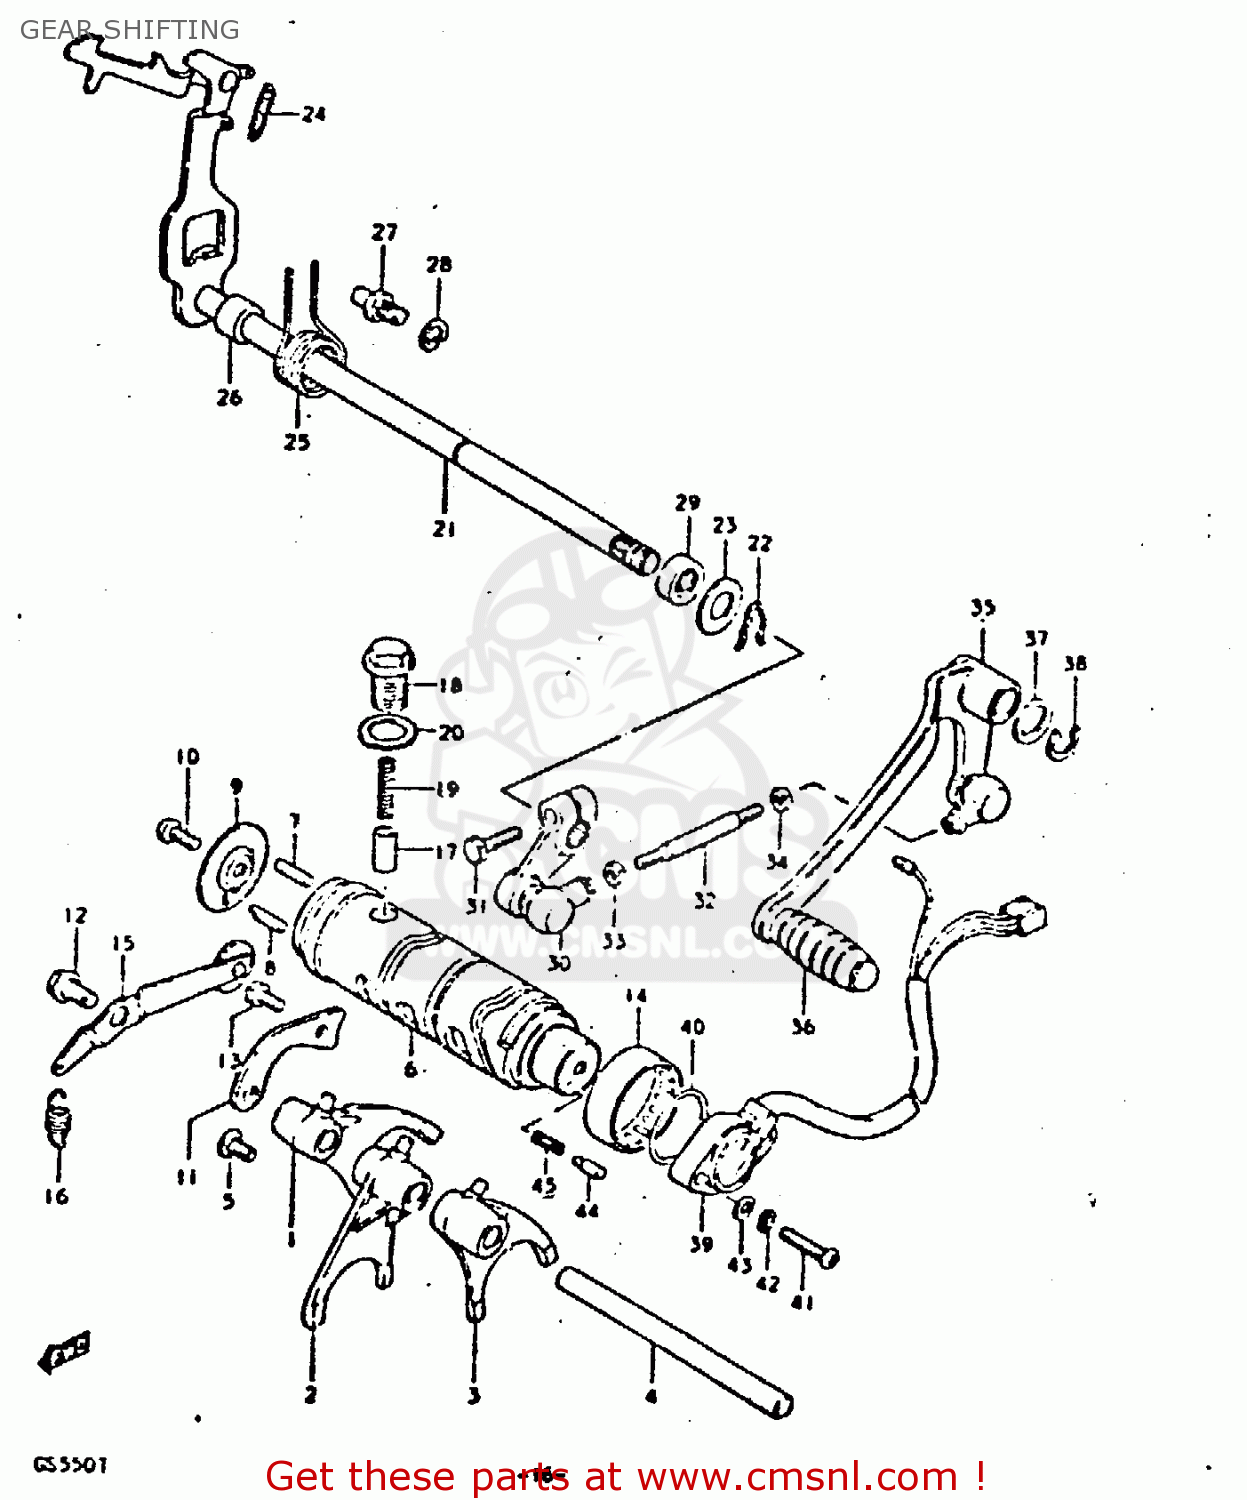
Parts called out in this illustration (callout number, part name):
1	FORK,GEAR SHIFT NO.1
2	FORK,GEAR SHIFT NO.2
3	FORK,GEAR SHIFT NO.2
4	SHAFT,GEAR SHIFT FORK
5	SCREW
6	CAM,GEAR SHIFT
7	PIN(4X18.5)
8	PIN
9	RETAINER,GEAR SHIFT CAM DR PIN
10	SCREW
11	GUIDE,GEAR SHIFTING CABLE
12	BOLT
13	BOLT
14	BEARING(40X47X12)
15	STOPPER,GEAR SHIFT CAM NO.1
16	SPRING
17	STOPPER,GEAR SHIFT CAM NO.2
18	HOLDER,GEAR SHIFT CAM STOP SPR
19	SPRING
20	GASKET(14X19.2X2) (NAS)
21	SHAFT,GEAR SHIFT
22	SPRING,RETAINER
23	WASHER (12.5X27X1.6)
24	SPRING
25	SPRING
26	SPACER(12X20X15.3)
27	STOPPER,GEAR SHIFT CAM
28	WASHER
29	OIL SEAL
30	ARM,GEAR SHIFT LINK
31	BOLT
32	ROD,GEAR SHIFT LINK
33	NUT
34	NUT
35	LEVER ASSEMBLY,GEAR SHIFTING
36	RUBBER,GEAR SHIFT PEDAL
37	WASHER(12.5X20X1)
38	CIRCLIP
39	TERMINAL BASE ASSY,GEAR SHIFT
40	O-RING (D:2.4 ID:26.2)
41	SCREW 5X20
42	LOCK WASHER
43	WASHER
44	PIN(5X15.5)
45	SPRING
